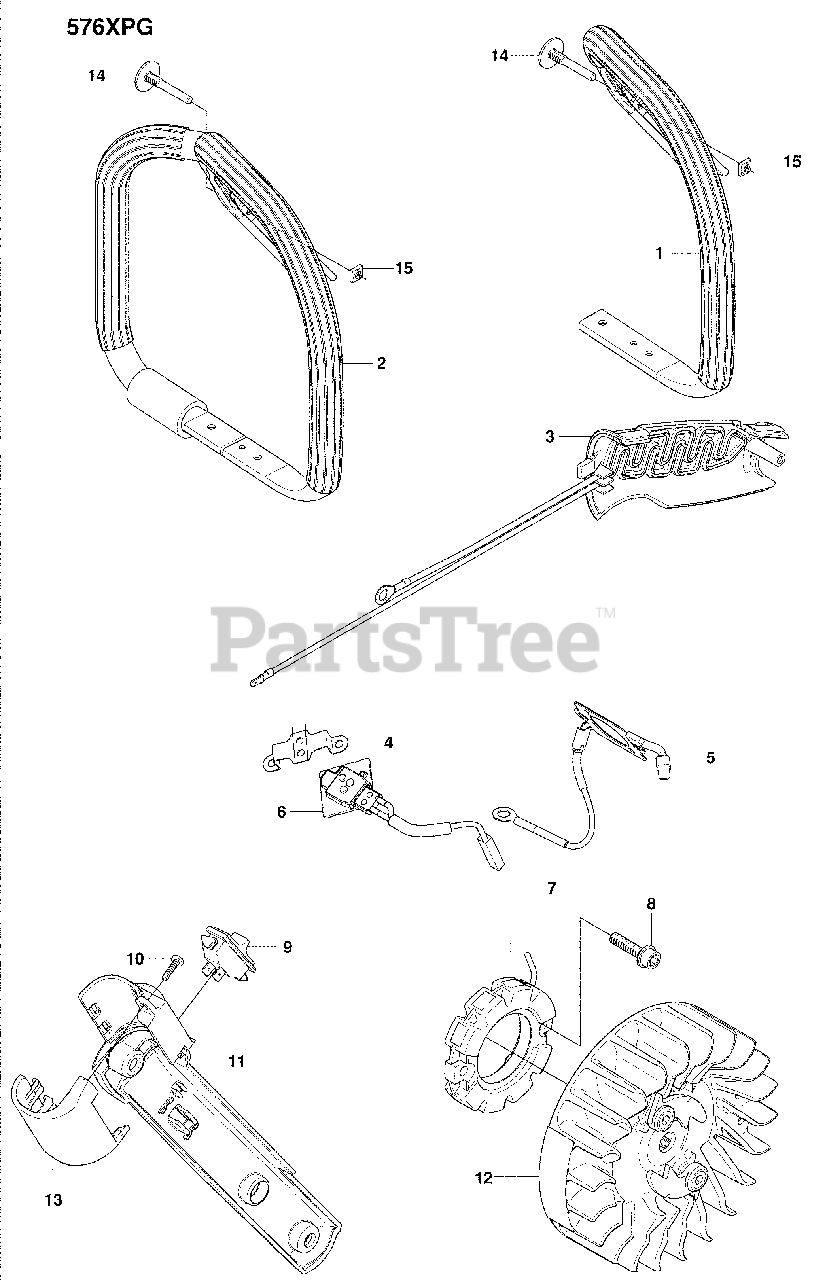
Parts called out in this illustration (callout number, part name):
1	Handle
2	HANDLE (WAG)
5	HANDLE CIRCUIT
6	THERMOSTAT
15	Square Nut
